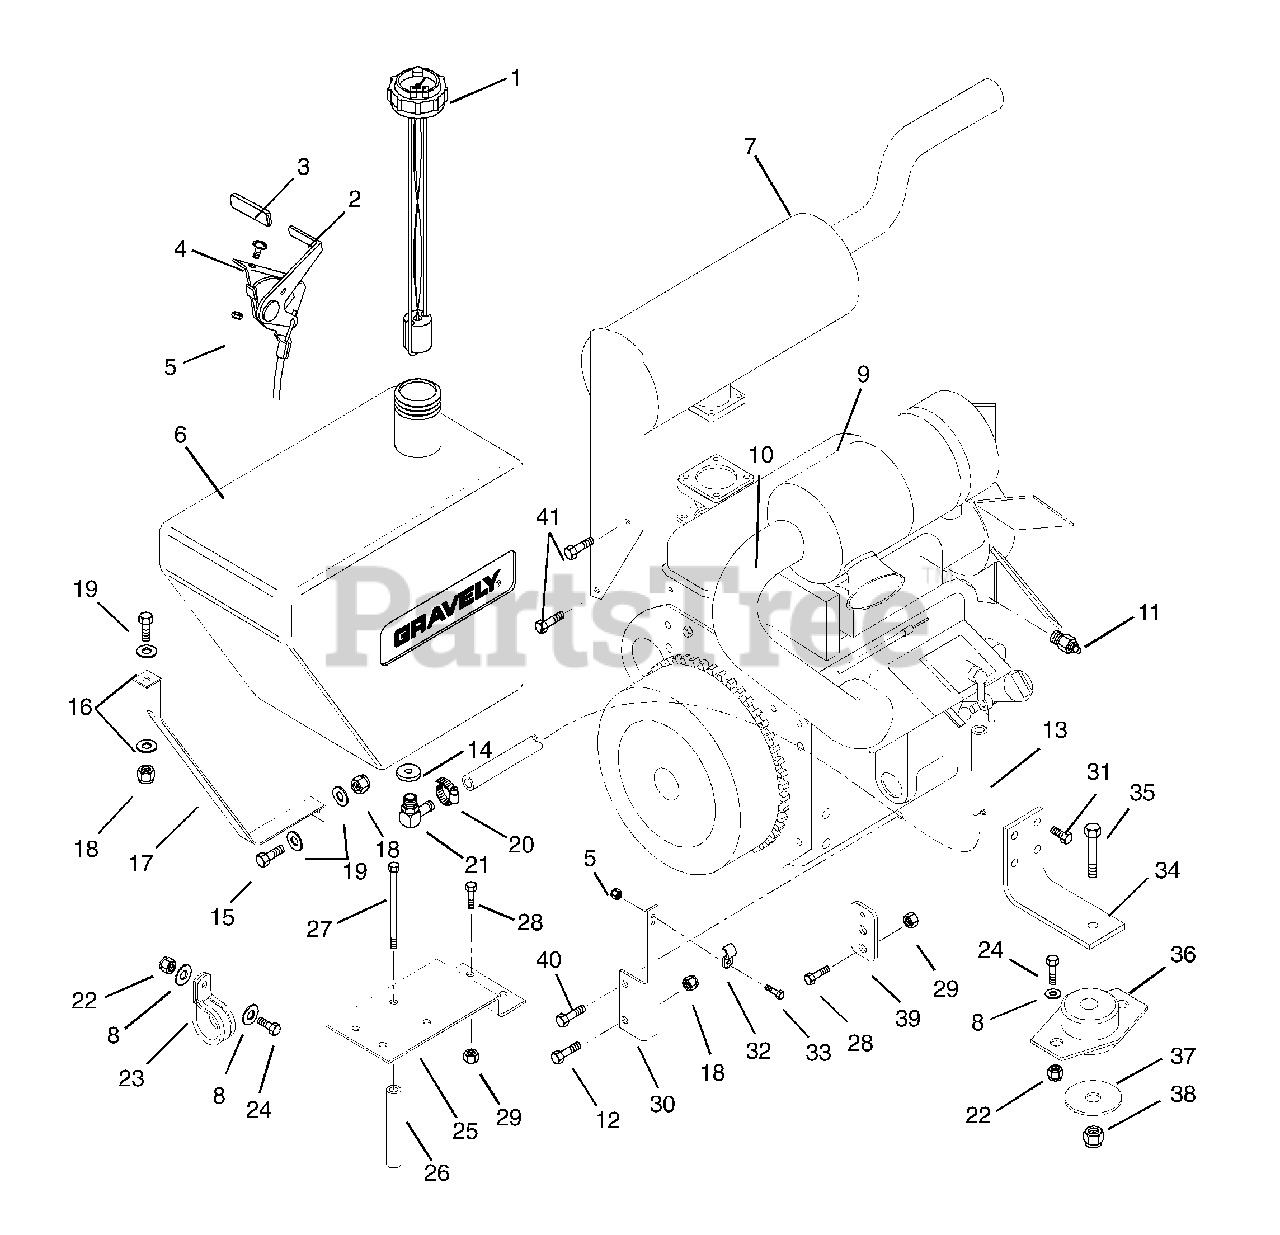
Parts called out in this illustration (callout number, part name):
1	Gauge, Fuel
2	Throttle Cable Assembly
4	Screw-Machine 10-24 x .50
5	Nut-Locking 10-24 w/Insert
6	Tank, Fuel
7	Muffler, Kubota
8	Washer-Flat-Steel .406 x .812 x .065
9	Engine, Kubota V-1305-B1
10	Hose, Air Intake
11	Sender, Temperature
12	Bolt-Hex .31-18 x 1.25 Grade 5
13	Gas Line-Bulk
14	Bushing
15	Bolt-Hex .31-18 x 2.00 Grade 5
16	Washer-Flat-Steel .344 x .688 x .065
17	Strap, Gas Tank
18	Nut-Locking-Nylon .31-18
19	Bolt-Hex .31-18 x .75 Grade 5
20	Hose Clamp
21	Fitting-Tank 1.37 x .406
22	Nut-Locking-Center .38-16
23	Clamp, Steel 1.0
24	Bolt-Hex .375-16 x 1.00 Grade 5
25	Bracket, Air Cleaner Mount
26	Mount, Engine
27	Bolt-Hex M8 - 1.25 x 120
28	Bolt-Hex .25-20 x .75 Grade 5
29	Nut-Locking-Center .25-20
30	Bracket, Throttle Cable
31	Bolt-Hex M10-1.25 x 25
32	Clip Plated
33	Screw-Machine 10-24 x .75
34	Mount, Engine
35	Bolt-Hex .50-13 x 2.75 Grade 5
36	Mount, Engine Isolator
37	Washer-Snub-Steel .53 x 2.38 x .125
38	Nut-Locking-Nylon .50-13
39	Clip, Throttle Cable
40	Bolt-Hex M10 x 1.25 x 20
41	Bolt-Hex M8 x 1.25 x 25 Grade 8
